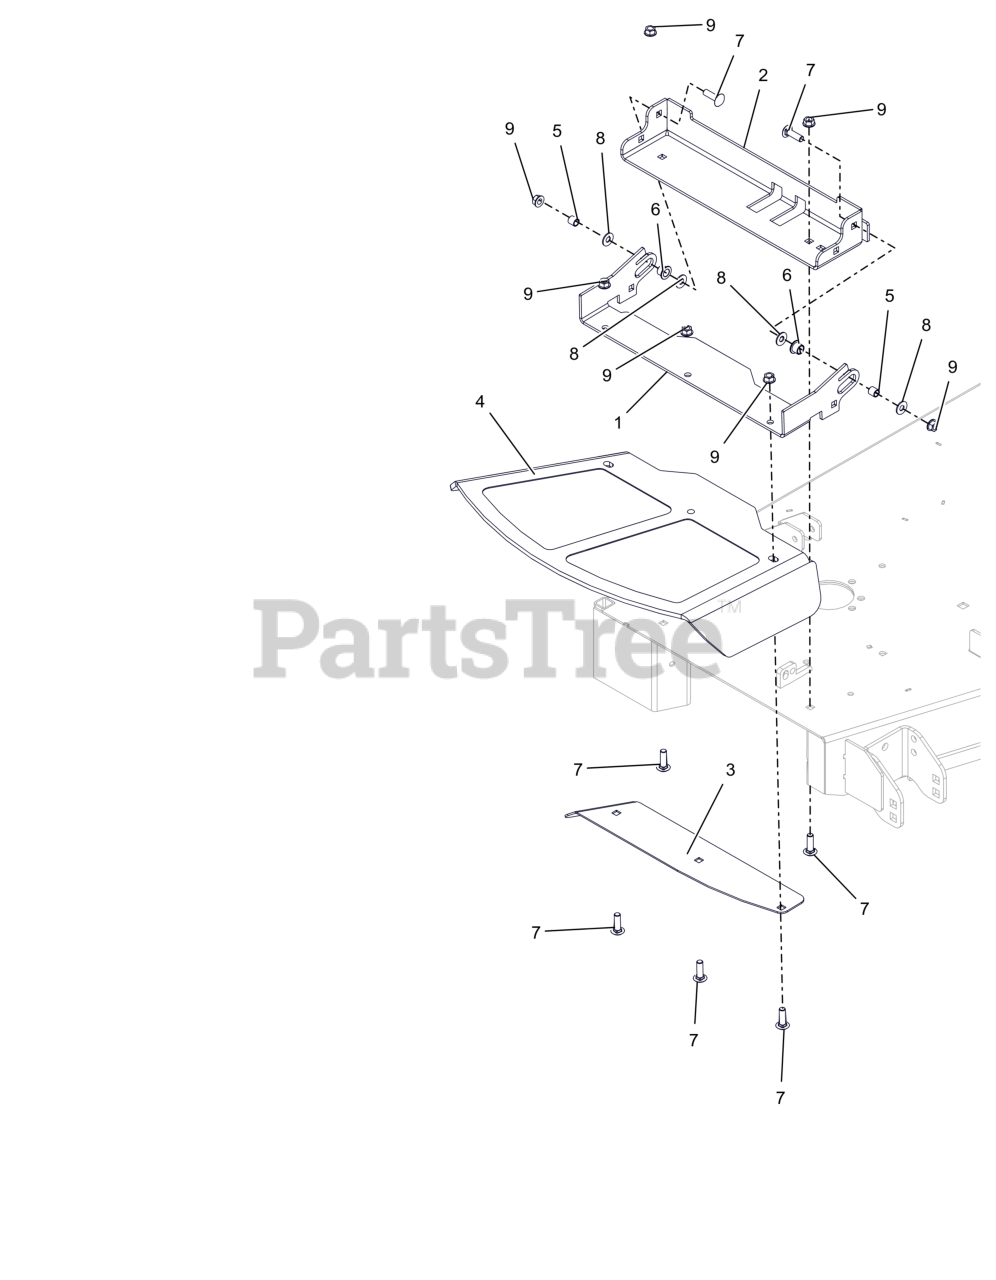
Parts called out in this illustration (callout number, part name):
1	BRKT, CHUTE MOUNT (ORANGE)
2	BASE, DISCHARGE CHUTE MTG BRKT (ORANGE)
3	48-60 DISCH CHUTE CLMP PLT-ORG
4	CHUTE, FORMED RUBBER DISCHARGE
5	SPCR, .385X.500X.350
6	BSHG, FLANGED .50X.625X.50X.062
7	BLT,RHSSN .38-16X1.25 G5 ZCC
8	WSHR, HDND .375X.875X.064 ZCC
9	NUT-LK-CTR-FLG .375-16 GF ZCC
